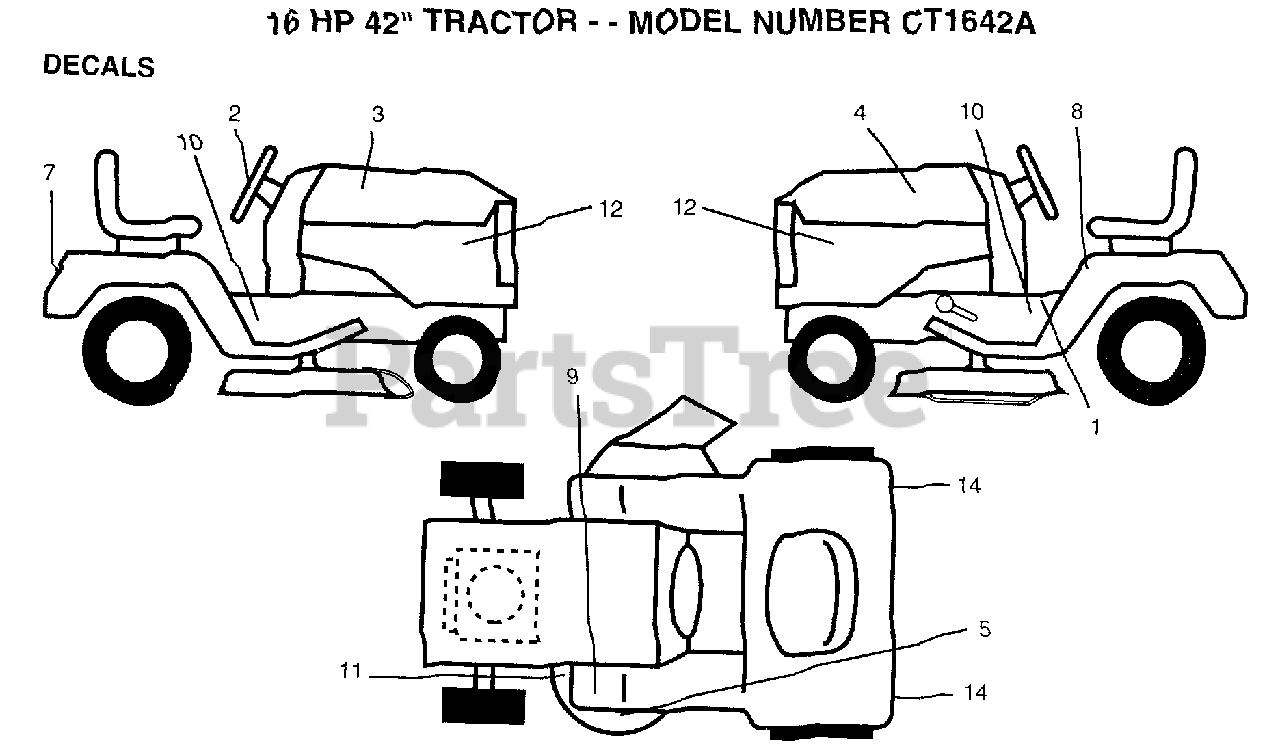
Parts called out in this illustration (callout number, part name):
2	DECAL INST STRWHL
3	DECAL.HD.RH.RALLY
4	DECAL.HD.LH.RALLY
7	DECAL.FENDER
8	DECAL
10	CHASSIS DECAL
11	DECAL.V.BELT
12	DECAL.HD.INS.
14	REFLECTOR-TAIL YT
